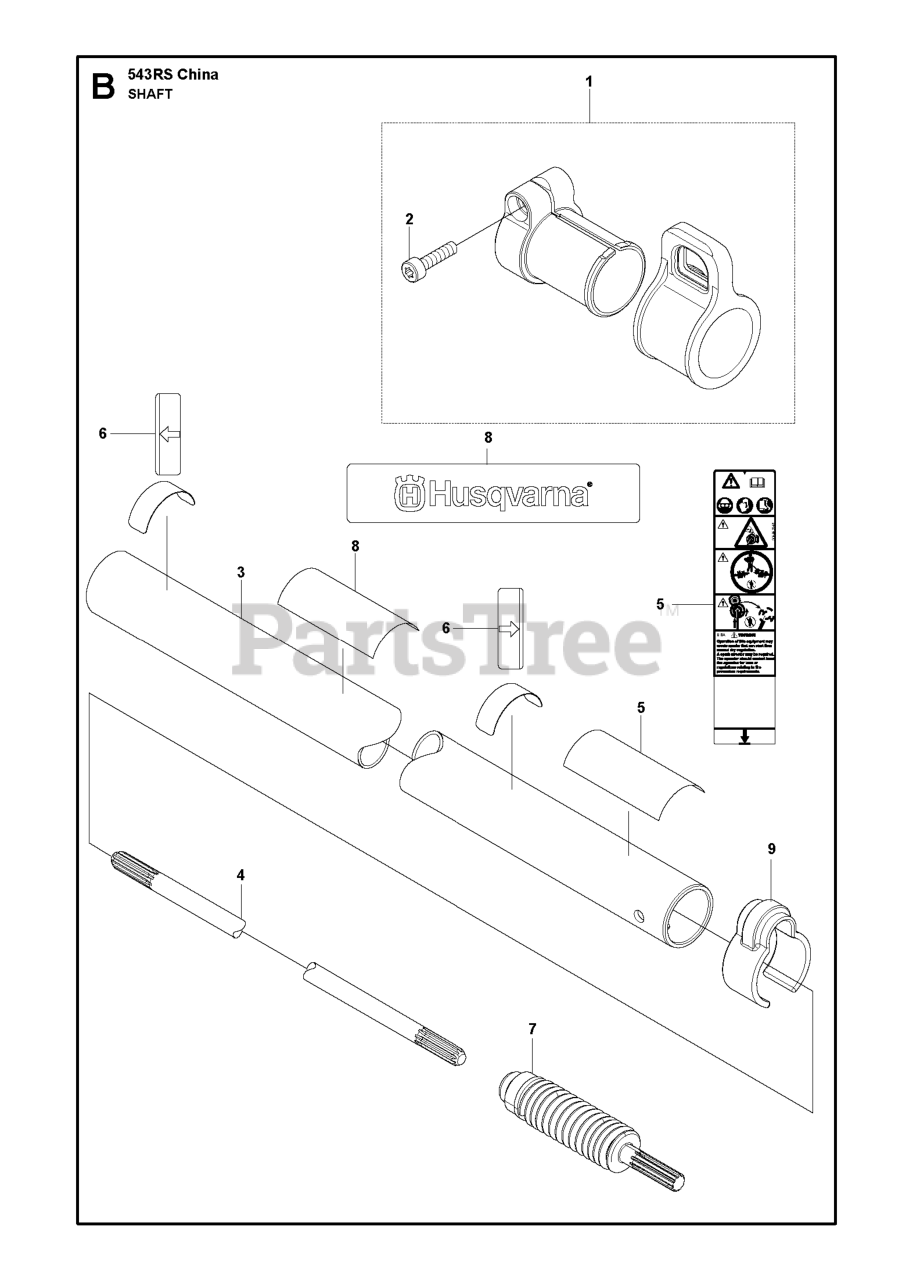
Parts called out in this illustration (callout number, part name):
1	HANGER ASSY.
2	BOLT
2	VALVE STEM LT
3	RIM ASM 6" FRONT SILVER
4	TUBE.16X6.5/7.5-8
5	LABEL WARNING TRIMMERS AND BRU
5	TIRE.15X6-6.TURF.MASTER.FRONT
6	FITTING LT
7	BEARING T
8	CAP, AXLE BLK
9	CLAMP
9	TIRE.20X10-8.TURF.MASTER.REAR
10	TUBE
11	RIM ASM 8" REAR SILVER
